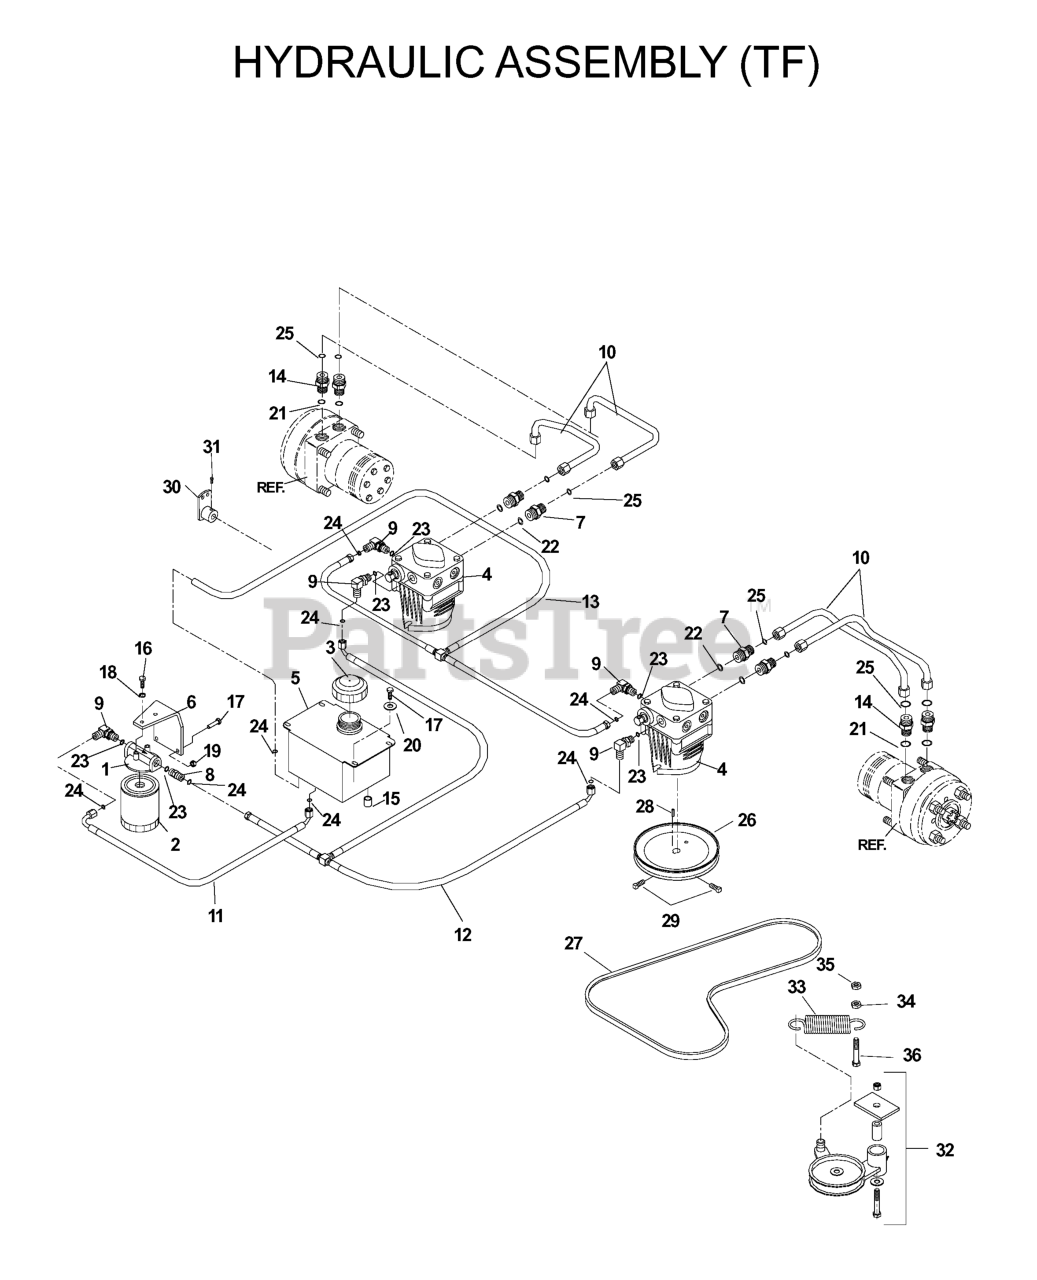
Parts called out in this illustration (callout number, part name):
1	FILTER HEAD
2	HYDRAULIC OIL FILTER
3	HYDRAULIC CAP
4	PUMP
6	OIL FILTER BRKT
7	FITTING, STRAIGHT F6400-8-8-0
8	STRAIGHT FITG
9	ELBOW, F6801-6-6-0 90 DEGREE
10	HYDRAULIC HOSE
12	TEE ASSEMBLY
13	TEE ASSEMBLY
15	NUT 9/16-18 JIC CAP
16	HCS 1/4C X 5/8
17	HCS 1/4C X 3/4 HCS
18	LOCKWASHER 1/4"
19	NUT.1/4-20.HEX.NYLOC.ZD
20	WASHER 1/4 FLAT
27	PUMP BELT
28	KEY 5 MM SQ X 25 MM
29	SCREW 5/16C X 5/8 SQ HEAD
30	PUMP LEVER
31	5/16C X 5/8 "V" POINT
32	IDLER ARM ASM
34	NUT 3/8C WHIZ
35	NUT 3/8-16 NYLOC
36	HCS 3/8C X 2
